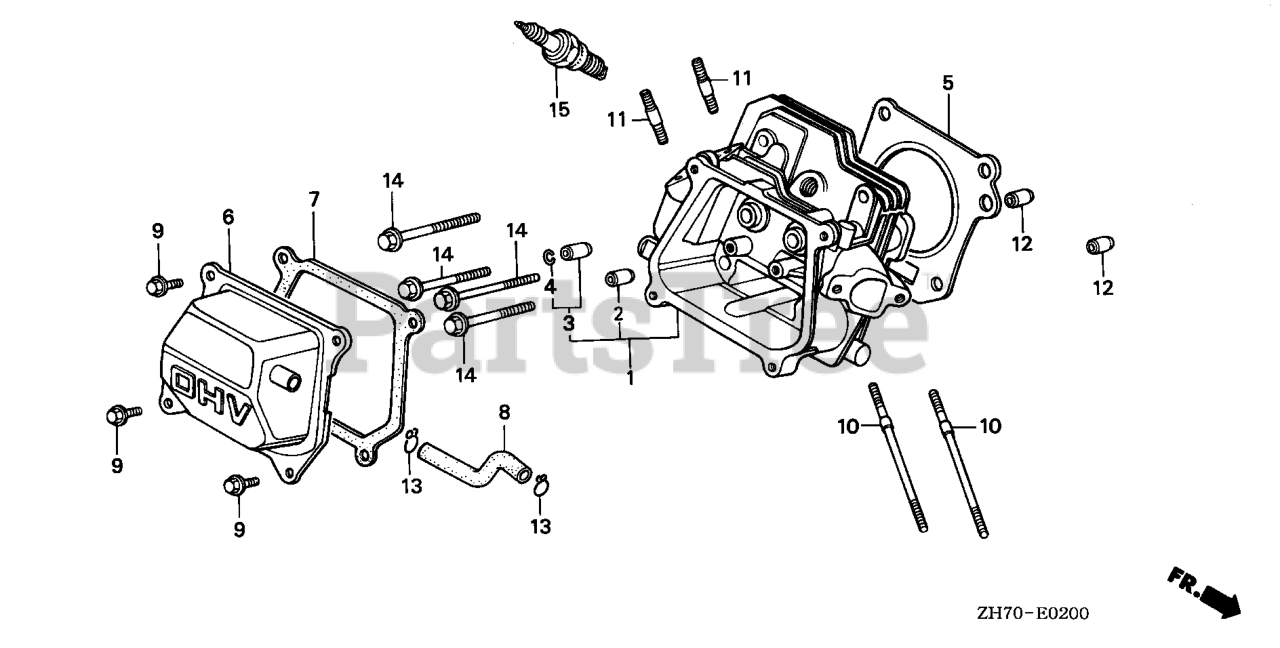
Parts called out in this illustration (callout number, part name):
1	CYLINDER HEAD
2	GUIDE, VALVE (OVER SIZE) Use up to Engine SN 2416541.
4	CLIP, VALVE GUIDE Use from Engine SN 1231803.
5	GASKET, CYLINDER HEAD
6	COVER, HEAD
7	GASKET, CYLINDER HEAD COVER
8	TUBE, BREATHER
9	BOLT, FLANGE (6X12) (CT200)
9	BOLT, FLANGE (6X13)
10	BOLT, STUD (6X109)
11	BOLT, STUD (8X32)
12	PIN A, DOWEL (10X16)
14	BOLT, FLANGE (8X55)
15	SPARK PLUG (BPR5ES) (NGK)
15	SPARK PLUG (W16EPR-U) (DENSO)
15	SPARK PLUG (BPR6ES) (NGK)
15	SPARK PLUG (W20EPR-U) (DENSO)
